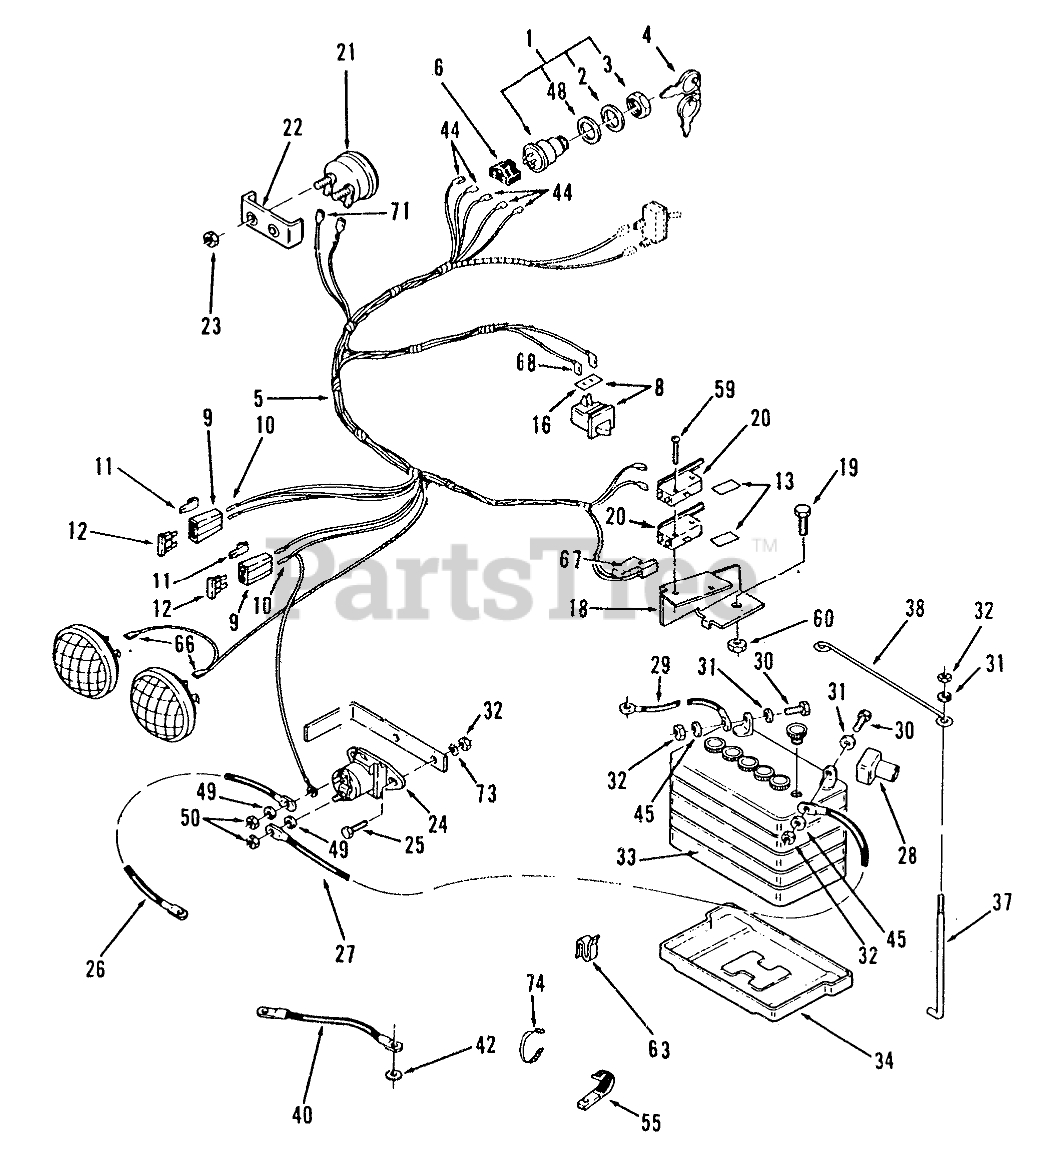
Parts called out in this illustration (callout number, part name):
1	IGNITION SWITCH ASM
2	LOCKWASHER
4	Ignition Key
5	WIRING HARNES
6	CONNECTOR-5 WAY-SERV
8	SWITCH INTERLOCK
9	AUTO-FUSEBLOCK TERM
10	TERMINAL FUSE
12	FUSE-BLADE, 15 AMP
13	BARRIER - SWITCH
16	SHIELD-DIRT SPST
18	Support-Switch
19	Bolt
20	SWITCH
21	Voltmeter (w/109650)
22	CLAMP MOUNTING
23	HEX NUT 10-32 E.S.
24	SOLENOID-STARTER
25	Screw
26	ASSY WIRE
27	CABLE-BLACK
28	Boot
29	ASSY WIRE
30	Bolt
32	Nut
33	Battery
34	TRAY BATTERY
38	ROD HOLD DOWN B
40	WIRE GROUND
42	Washer-Lock
44	Terminal
45	Washer
48	Washer
49	Washer
50	Nut
55	CLIP
59	Screw
60	NUT HEX 4-40 ELAST
63	CLIP-CABLE
67	CONNECTOR BODY
68	Terminal
71	TERMINAL-TAB RCPT
73	LOCKWASHER
74	PLASTIC TIE
